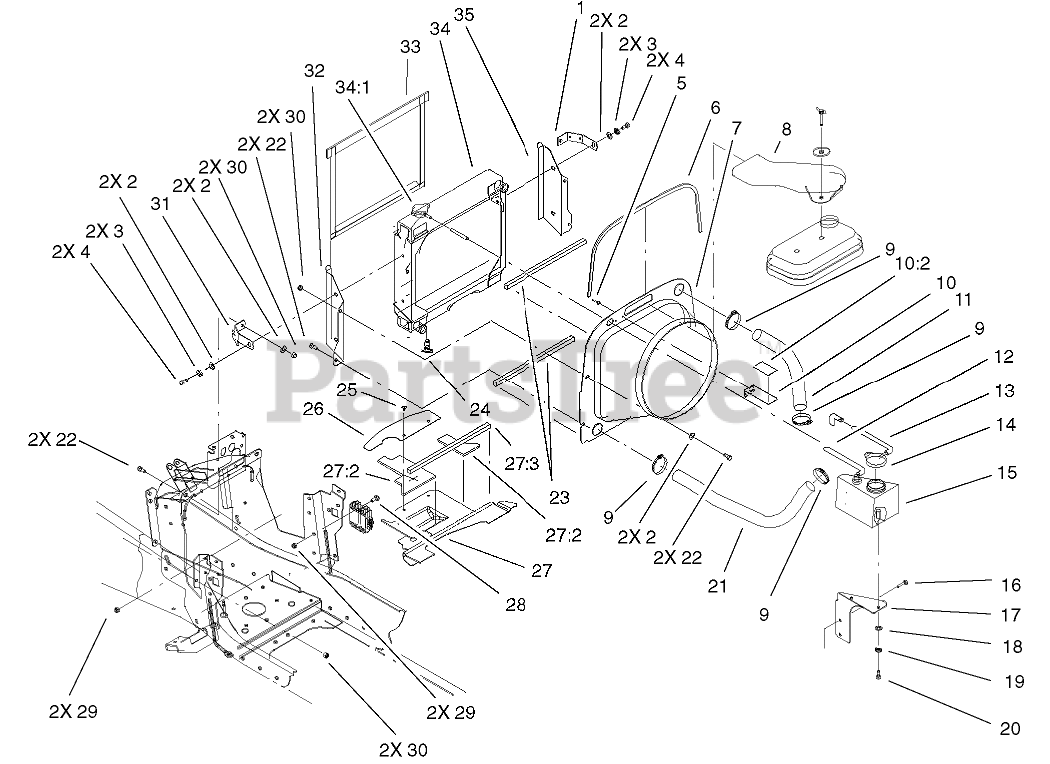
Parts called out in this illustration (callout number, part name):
1	Strap-Radiator
2	WASHER-PLAIN
3	WASHER-LOCK
4	SCREW-HH
5	RIVET-POP
6	TRIM - LOC 31"
7	SHROUD - FAN
8	DUCT - AIR, KAWASAKI
9	CLAMP-HOSE
10	FAN/DECAL ASM
10:2	DECAL - WARNING
11	HOSE - RAD. KAWASKI
12	HOSE - FUEL LINE
13	HOSE - OVERFLOW
14	CAP - COOLANT RESERVOIR
15	BOTTLE - OVERFLOW
16	BOLT-CARR
17	Brkt-Bottle
18	WASHER-FLAT
19	WASHER-LOCK
20	SCREW-HH
21	HOSE - RAD. KAWASKI
22	SCREW-HH
23	FOAM - RADIATOR/SHROUD
24	VALVE - DRAIN
25	RIVET - PLASTIC
26	BAFFLE - TOWER REAR
27	BAFFLE-TOWER ASM
27:2	FOAM - BAFFLE
27:3	FOAM - RADIATOR/SHROUD
28	SCREW-HH
29	NUT-HEX
30	NUT-LOCK, NI
31	Bracket-Relay
32	Support-Radiator RH
33	SCREEN - CHAFF
34	RADIATOR - GAS
34:1	CAP-RADIATOR
35	Support-LH Radiator
